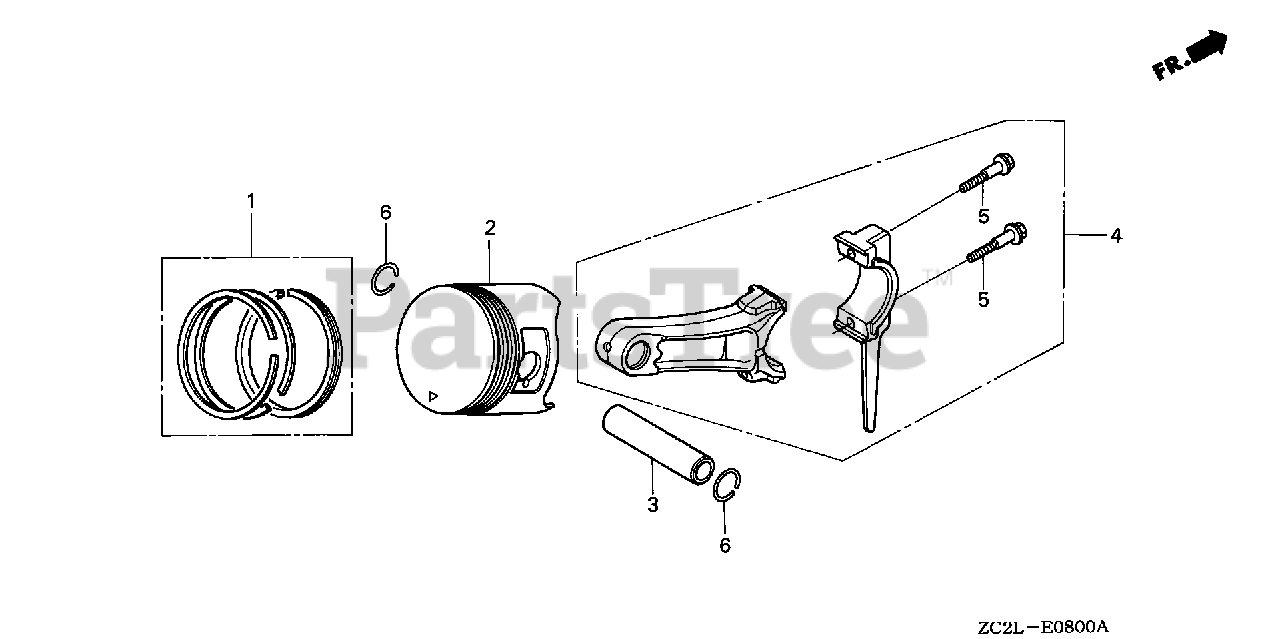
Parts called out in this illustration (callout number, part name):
1	RING SET, PISTON (STD) (NIPPON)
1	RING SET, PISTON (0.25) (NIPPON)
1	RING SET, PISTON (0.50) (NIPPON)
1	RING SET, PISTON (0.75) (NIPPON)
1	RING SET, PISTON (STD) (TPR)
1	RING SET, PISTON (0.25) (TPR)
1	RING SET, PISTON (0.50) (TPR)
1	RING SET, PISTON (0.75) (TPR)
2	PISTON (STD)
2	PISTON (0.25)
2	PISTON (0.50)
2	PISTON (0.75)
3	PIN, PISTON
4	ROD ASSY., CONNECTING (STD)
4	ROD ASSY., CONNECTING (0.25 LOWER SIZE)
5	BOLT, CONNECTING ROD
6	CLIP, PISTON PIN (20MM)
